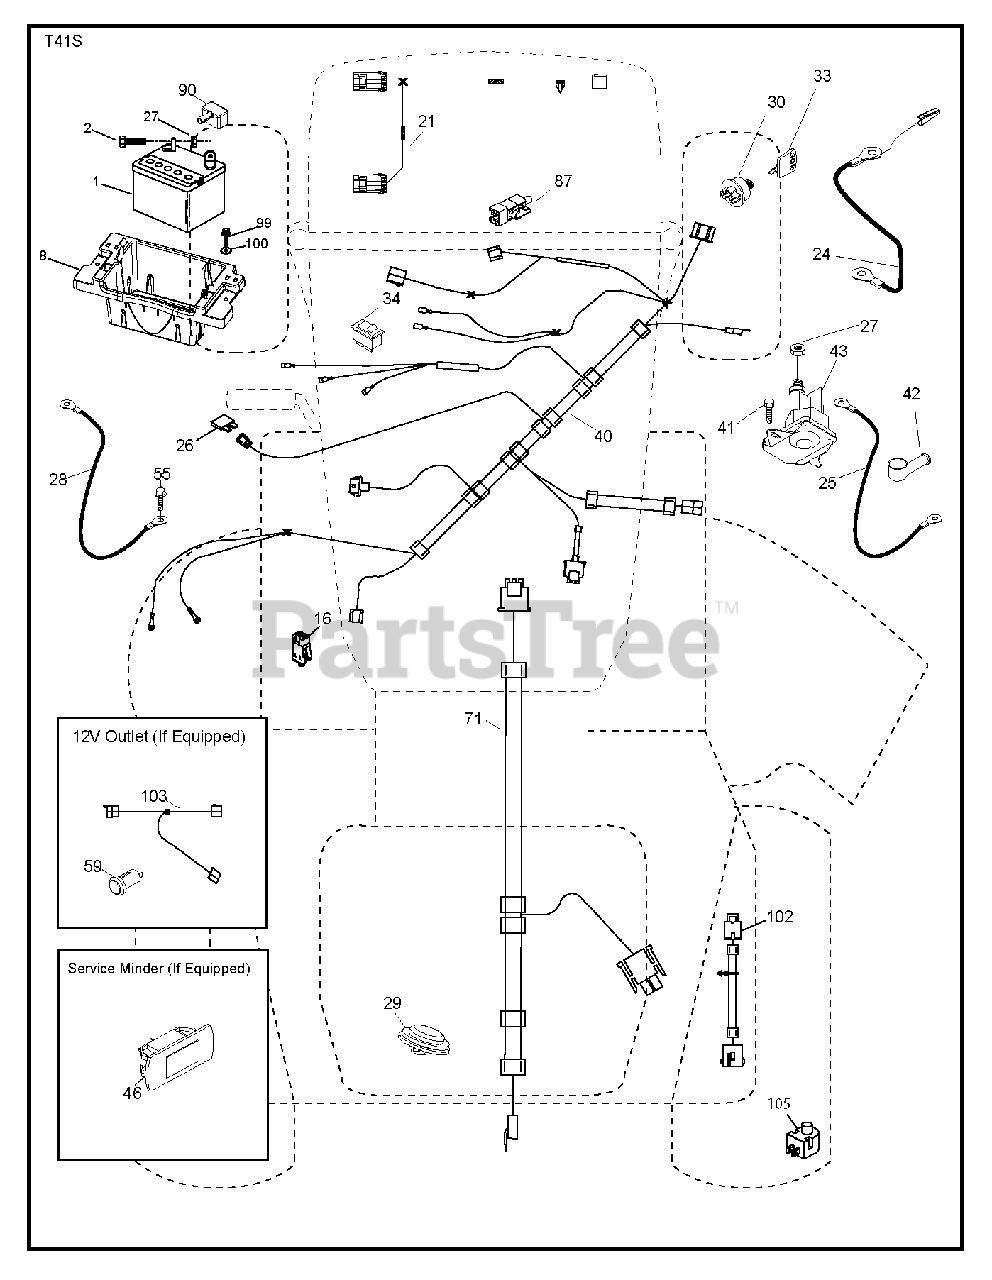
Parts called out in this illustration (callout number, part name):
1	Battery, Dry 30 Amp
2	BOLT.HEX.1/4.X.3/4.DICHROMATE
8	TRAY.ASM.BATTERY.FRT.TEX.CARB
16	SWITCH INTERLOOK PUSH-IN
21	HARNESS LIGHT ASSY TRACTOR,
24	CABLE.FRBATT.W/WIRE.8GA.8
25	CABLE.STARTER.8GA.17.5
26	FUSE 20AMP
27	NUT
28	CABLE.GROUND.21"BLK.8GA.90T
29	SWITCH.SEAT.DELTA.OPC.
30	SWITCH.IGN.DELTA.W.LGH.ROS
33	KEY.CHAIN.BLISTER.PACK.GEN.USA
40	HARNESS.IGN.DASH.CBL.YTGT.PRED
41	SCREW
42	TERMINAL COVER
43	SOLENOID.STARTER.BRASS.PLUNGER
46	GUAGE.SRVCMNDR.HRMTR.
55	SCREW 5/16"
71	HARNESS-CHASSIS SUB
87	SWITCH.INTRLCK.CLUTCH.
90	COVER.TERMINAL.BATTERY
99	SCREW HEXWSHR 1/4-20X3/4
102	HARNESS PIGTAIL PCH TEX ROS
105	REVERSE SWITCH
